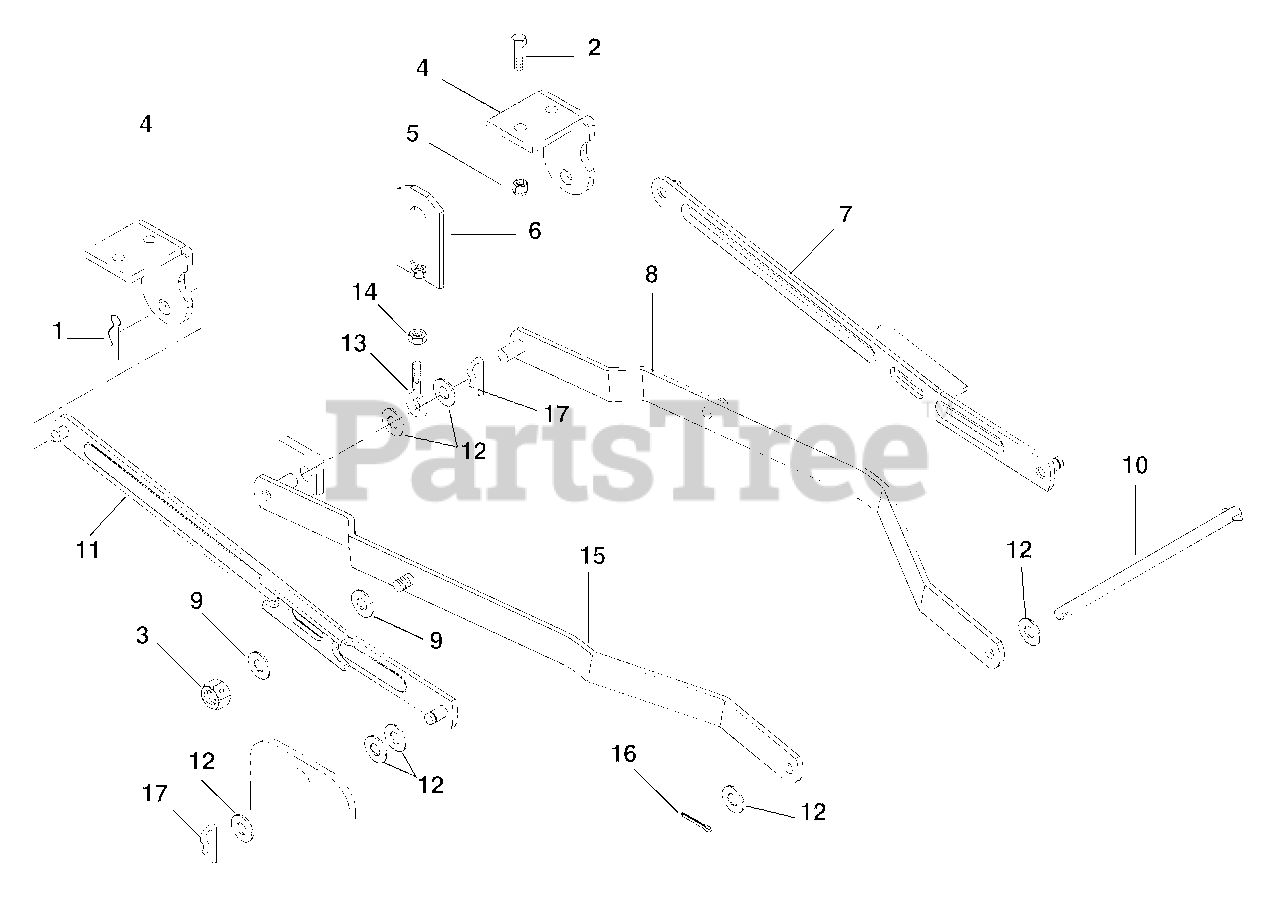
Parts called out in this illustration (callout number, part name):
1	Pin-Hair External .12 x .31 x 2.37
2	Bolt-Hex .38-16 x .75 Grade 5
3	Nut-Locking-Center .625-11
4	Rear Hanger
5	Nut-Locking-Center .375-16
6	Weldment, Adjustment Link
7	Hanger, Rear Left Hand
8	Arm, Lift Left Hand
9	Washer-Flat-Steel .656 x .31 x .095
11	Hanger, Rear Right Hand
12	Washer-Flat-Steel .531 x 1.25 x .10
14	Nut-Jam .375-16
15	Arm, Lift Right Hand
16	Pin-Cotter .16 x 1.00
17	Clip, Spring
